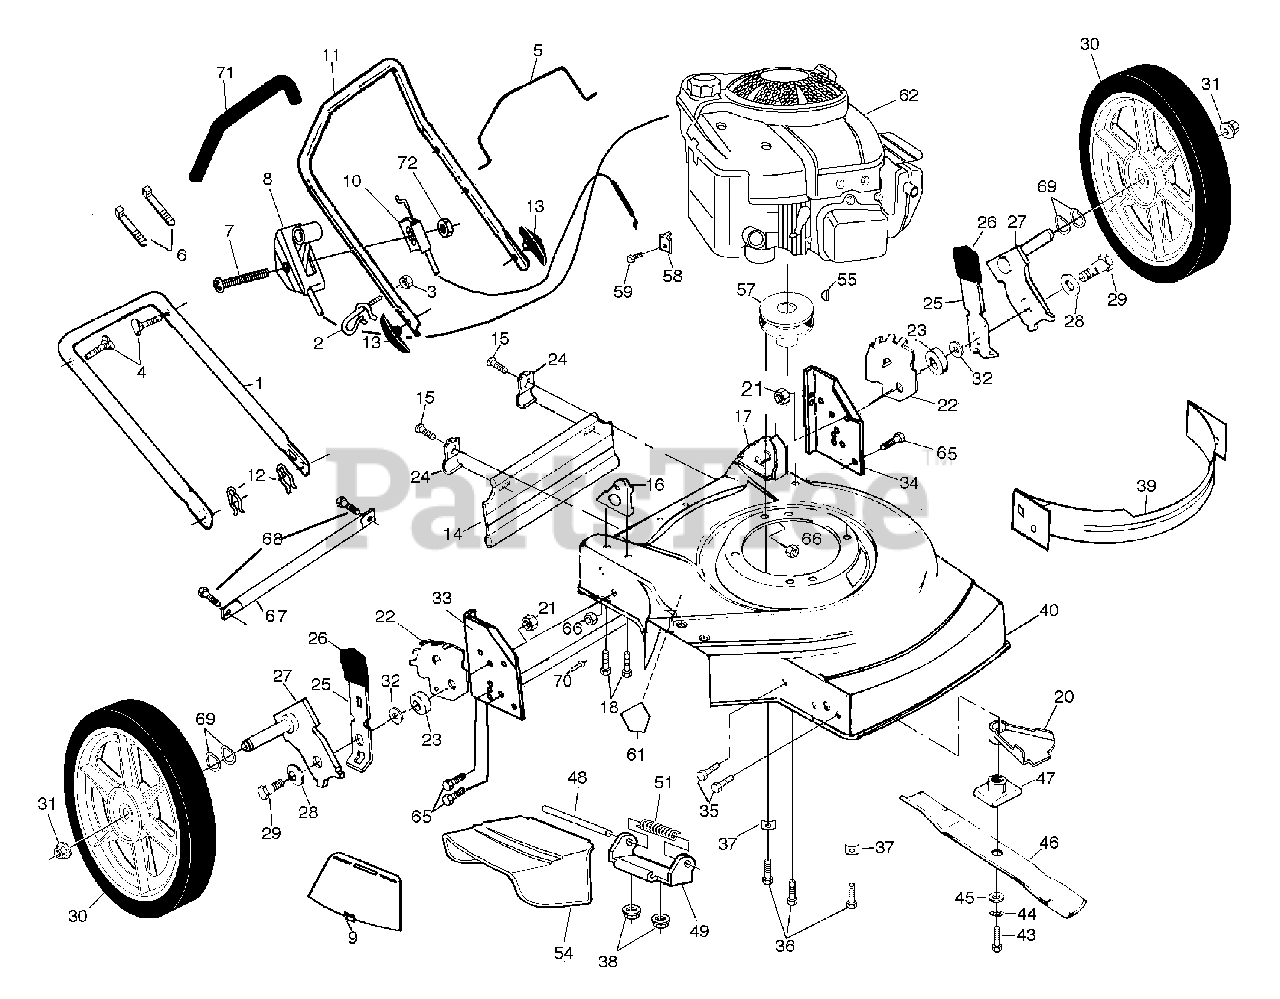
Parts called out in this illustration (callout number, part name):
1	Lower Handle
2	Rope Guide
3	Locknut 1/4-20
4	Handle Bolt
5	Control Bar
6	Wire Ties
7	Hex Washer Head Screw 1/4-20 x 2-1/8
8	Throttle Control
9	Mulcher Plate
10	Engine Zone Control Cable
11	Upper Handle
12	Hairpin Cotter
13	Handle Knobs
14	Rear Skirt
15	Hex Head Screw
16	Handle Bracket Assembly (Right)
17	Handle Bracket Assembly (Left)
18	Screw 5/16-18 x 3/4
20	Debris Shield
21	Locknut
22	Wheel Adjusting Bracket
23	Spacer
24	Skirt Bracket
25	Selector Spring
26	Selector Knob
27	Axle Arm Assembly
28	Belleville Washer
29	Shoulder Bolt 3/8-16
30	Wheel & Tire Assembly (Rear)
31	Flanged Locknut 3/8-16
32	Flat Washer
33	Wheel Support Bracket (RT)
34	Wheel Support Bracket (LT)
36	Thread Rolling Screw 3/8-16 x 1
37	Engine Washer
38	Nut
39	Front Baffle Kit
40	Mower Housing Kit
43	Hex Head Screw 3/8-24 x 1-3/8 Gr. 8
44	Helical Washer 3/8
45	Hardened Washer
47	Blade Adapter
49	Housing Bracket
51	Torsion Spring
54	Discharge Guard
55	Hi-Pro Key
57	Engine Pulley
58	Cable Clamp
59	Screw #10 x 5/8
61	Danger Decal
66	Nut
67	Support Rod
68	Screw hex Tap. 1/4/20
69	Wave Washer
71	Foam Grip
72	Nut, Hex 1/4-20
